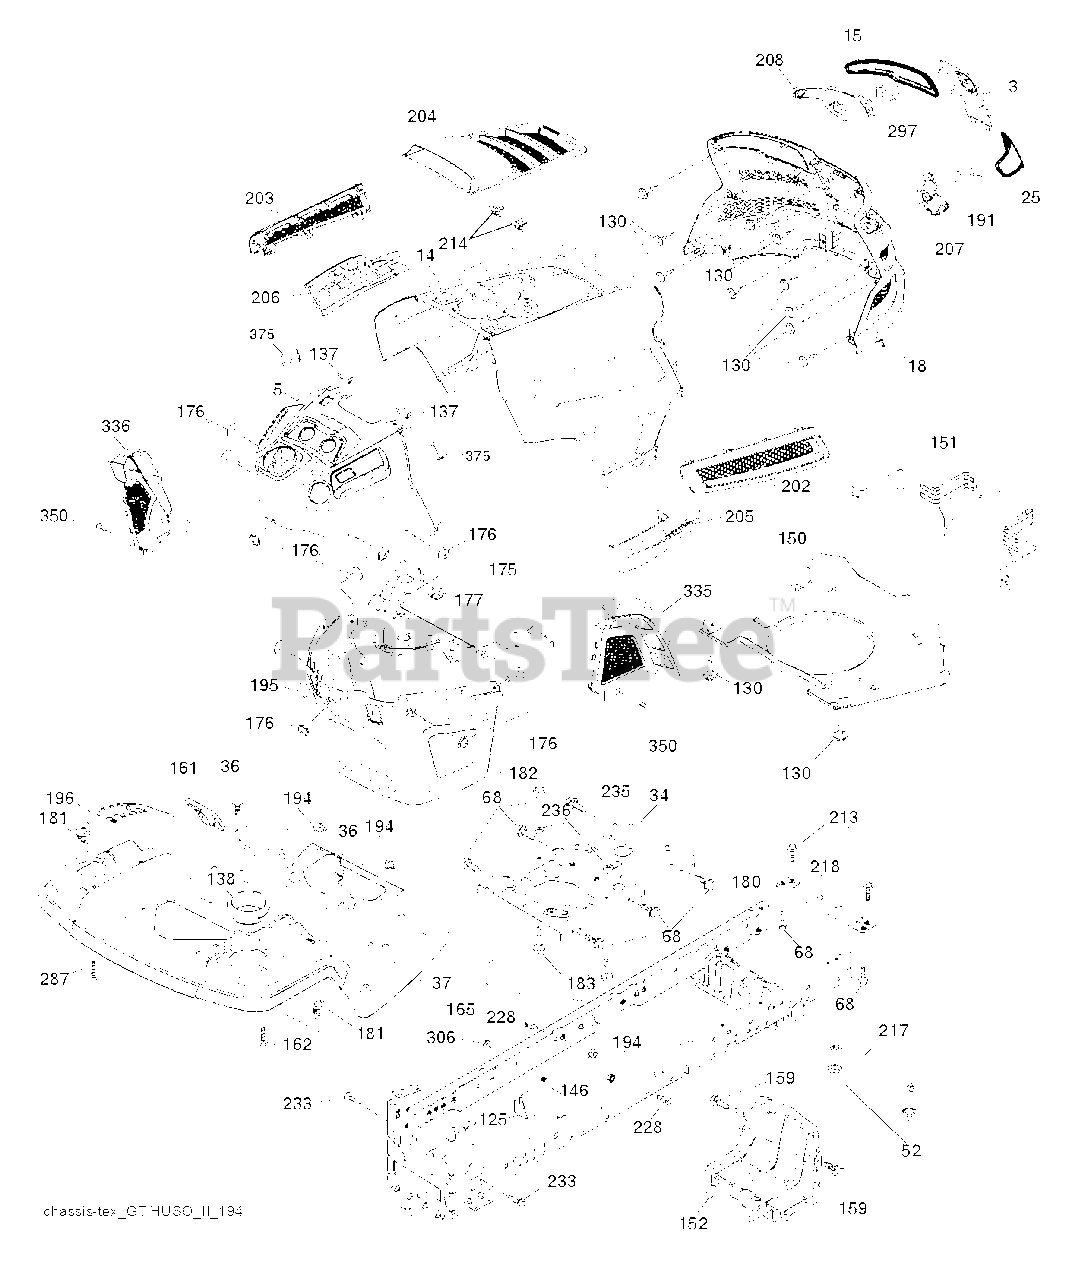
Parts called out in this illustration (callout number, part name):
3	APPLIQUE.SUBASM.GT.HUSQ.II
5	DASH.UPP.GT2.DUAL.RD.PT
14	HOOD.ASM.HUSQVARNA.GT.TEX.ORAN
15	LENS.HEADLIGHT.LH.GTII.2011
18	GRILLE SUBASM.GT.II.LOW.HDLGHT
25	LENS.HEADLIGHT.RH.GTII.2011
34	PLATE.ENGINE.WELDED.CHASSIS
36	SCREW 5/16"
37	FENDER.ERGO.LT.W/CPH.W/FW.ORNG
52	LOCKNUT
68	SCREW LT
125	CLIP.FUEL.LINE
130	SCREW.#10 X 0.750.BOS
137	BUMPER DASH
138	HOLDER.CUP.LT.GREY
146	BOLT.RDHD.SHT.SQNK.3/8-16X5/8
150	AIR.DUCT.GTV.BLACK
151	BRACKET.PIVOT.HOOD.GT.HUSQ.II
152	SHIELD.BROWNING.PNT.GT.V2
159	SCREW, 3/8-16X3/4
161	WINDOW.FUEL.LT.HUSQ.TEX.498
162	SCREW.HI-LO.CONSOLE
165	SUPPORT.TANK.REAR.W/TEX
175	PLATE.CROSSMEMBER.HUSQ
176	SCREW.#10-24X5/8.RN.QU
177	BUSHING STEERING
180	CHASSIS
181	BUSHING.MNT.FEND.CRGO.TEX.49
182	DASH.LOWER.COMMON.12V.ADAPTOR
183	BOLT.5/16-18X1-1/4 FULL THD
191	INSERT.REFLECTIVE.RH.HUSQ.GTII
194	NUT LOCK HEX FLANGE 5/16-18
195	PLUG.HOLE.DASH.LOWER.12V.BLK
196	DECKLFT.CONSOL FULL ASSM GREY
202	VENT.SIDE.RH.GT.HUSQ.II.
203	VENT.SIDE.LH.GT.HUSQ.II.498
204	VENT.TOP.HUSQ.GT2
205	SIDE.TRIM.RH.GT.HUSQ.II
206	SIDE.TRIM.LH.GT.HUSQ.II.GRAY
207	HEADLIGHT.CUP.BEZEL.HUS.GT2.RH
208	HEADLIGHT.CUP.BEZEL.HUS.GT2.LH
213	BOLT
214	CLIP.RETAINER.TINNER.
217	ROD.PIVOT.HOOD
218	X-PIECE.HOOD.STOP.NON/
228	STUD.FASTNER.W/ANTI-ROTATE
233	BOLT.SHOULDER
235	SPACER FENDER
236	NUT.CENTERLOCK.5/16-
287	SCREW 1/4X20
297	INSERT.REFLECTIVE.LH.HUSQ.GTII
306	NUT LOCK FLG 3/8-16 UNC
335	COVER.LOWER.DASH.RH.BLACK
336	COVER-LH.LOWER.DASH.GT2.BLACK
350	CLIP.X-MAS.TREE
375	BUMPER CLIP-ON. DASH 1"
